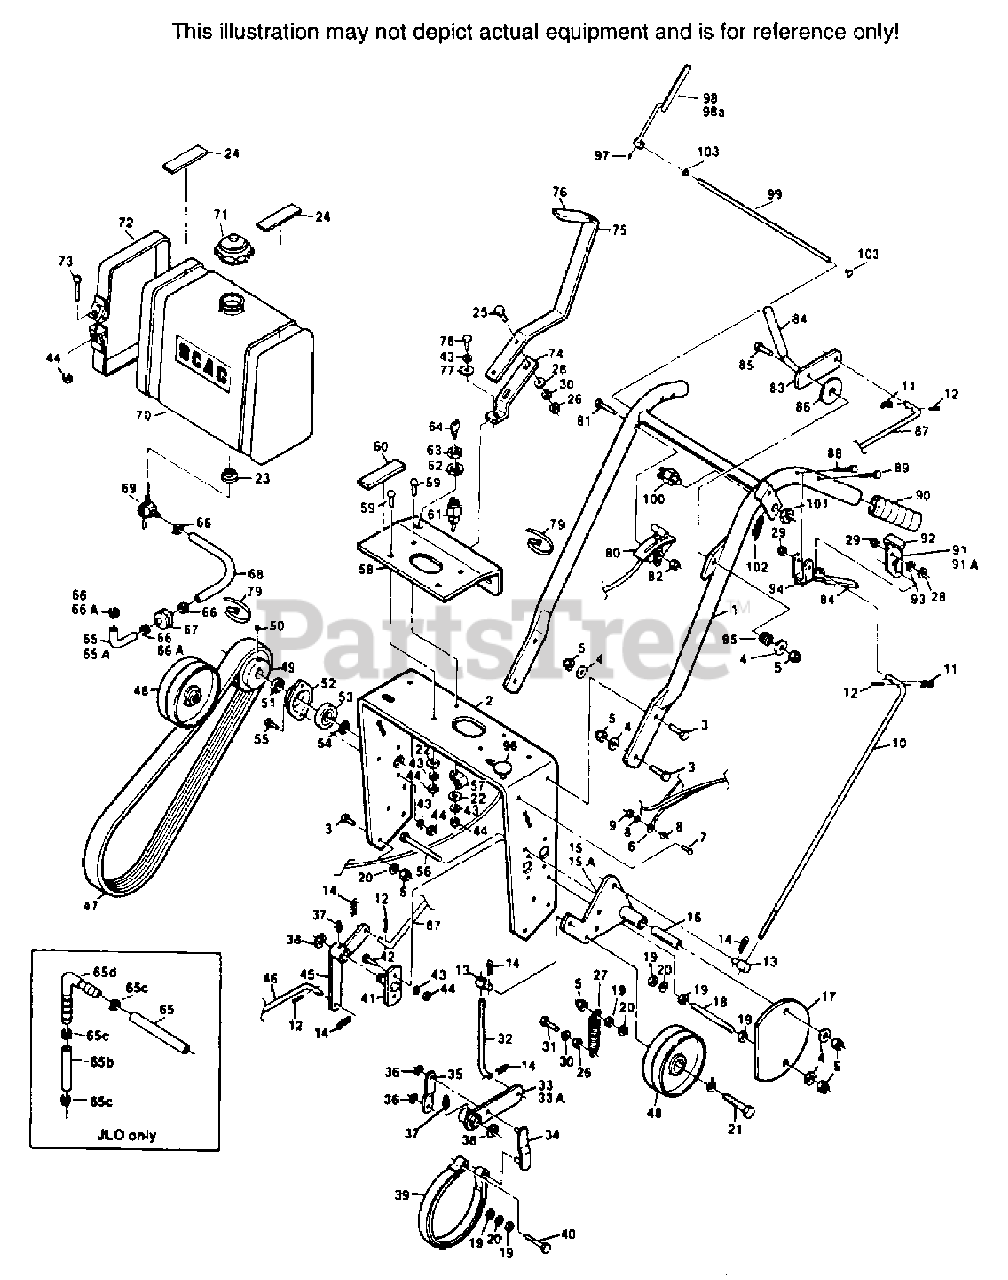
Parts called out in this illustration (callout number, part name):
1	HANDLE ASSY.(INCL. 90 & DECALS)
2	HANDLE MOUNTING FRAME
4	WASHER, 25/64 X 15/16 X 12 GA.
5	HEX NUT, 3/8-16 ELASTIC STOP
6	WIRE HARNESS
8	LOCKWASHER, #10 EXT. TOOTH
10	CONTROL ROD, STEERING
11	HAIR PIN, SMALL
13	SWIVEL JOINT
14	HAIR PIN, LARGE
15	IDLER BRACKET WLD, RH
15A	IDLER BRACKET WLD, LH
16	IDLER SLEEVE
17	BELT GUARD
18	SUPPORT BELT GUARD
23	BUSHING
24	RUBBER PADS(UPPER)
25A	CARRIAGE 1/4-20 X 1
27	SPRING, IDLER TENSION
28	WASHER, 11/32 X 11/16 X 16 GA.
29	HEX NUT, 5/16-18 ELASTIC STOP
32	BRAKE ROAD
33	BRAKE LEVER WLD, RH
33A	BRAKE LEVER WLD, LH
34	BRAKE LINK WLD.
35	BRAKE LINK
36	NUT, PUSH-ON, 3/8
37	GREASE FITTING, STR., 1/4-28
38	REAINING RING, 5/8 EXT.-"E"
39	BRAKE BAND
41	BELL CRANK PIVOT WLD.
45	BELL CRANK WLD, CLUTCH
46	BLADE CLUTCH ROD, LOWER
47	BELT, WHEEL DRIVE
48	IDLER PULLEY, WHEEL DRIVE
49	PULLEY, JACKSHAFT(INCL. 50)
51	SPACER, JACKSHAFT PULLEY
52	FLANGE, JACKSHAFT BEARING
53	BEARING, JACKSHAFT
54	RETAINING RING, 5/8 EXT.-BASIC
57	CLAMP
58	SHIFTER PLATE
60	RUBBER PAD(LOWER)
61	KEY SWITCH
62	LOCKWASHER, INTERNAL TOOTH, 5/8
63	HEX NUT, 5/8-32
64	KEY, IGNITION
66	CLAMP, FUEL HOSE
67	FUEL FILTER
68	FUEL HOSE, LONG 1/4 ID X 17"
69	VALVE, FUEL SHUT OFF
70	FUEL TANK ASSY.(INCL. DECALS 23,71,69)
71	FUEL TANK CAP
72	STRAP, FUEL TANK
74	SHIFTER LEVER
75	SHIFT LEVER ASSY.(INCL. 76)
76	GRIP, SHIFT LEVER
77	WASHER, 17/64 X 7/8 X 1/8 HT
78	HEX HEAD BOLT, 1/4-28 X 3/4 GRADE 8
79	CABLE TIE
80	THROTTLE CONTROL
82	HEX NUT, 1/4-20 ELASTIC STOP
83	BLADE CLUTCH LEVER ASSY.(INCL. 84)
84	GRIP, LEVER
86	WASHER, 3/8 X 2 X 16 GA.
87	BELT CLUTCH ROD, UPPER
90	GRIP, HANDLE
91	NEUTRAL LATCH ASSY, RH(INCL. 92)
91A	NEUTRAL LATCH ASSY, LH(INCL. 92)
92	GRIP, NEUTRAL LATCH
93	CURVED SPRING WASHER
94	BRAKE LEVER ASSY.(INCL. 84)
95	SPRING COMPRESSION
97	SET SCREW 1/4-28 X 1/4 KNURLED CUP PT.
98	SAFETY INTERLOCK HAND GRIP LH
98A	SAFETY INTERLOCK HAND GRIP RH
99	ROD, CONTROL PIVOT - 16"
100	SWITCH INTERLOCK
101	HEX NUT 9/16-18, STEEL SPRING
102	SPRING, GRIP RETURN
103	BUSHINGS
